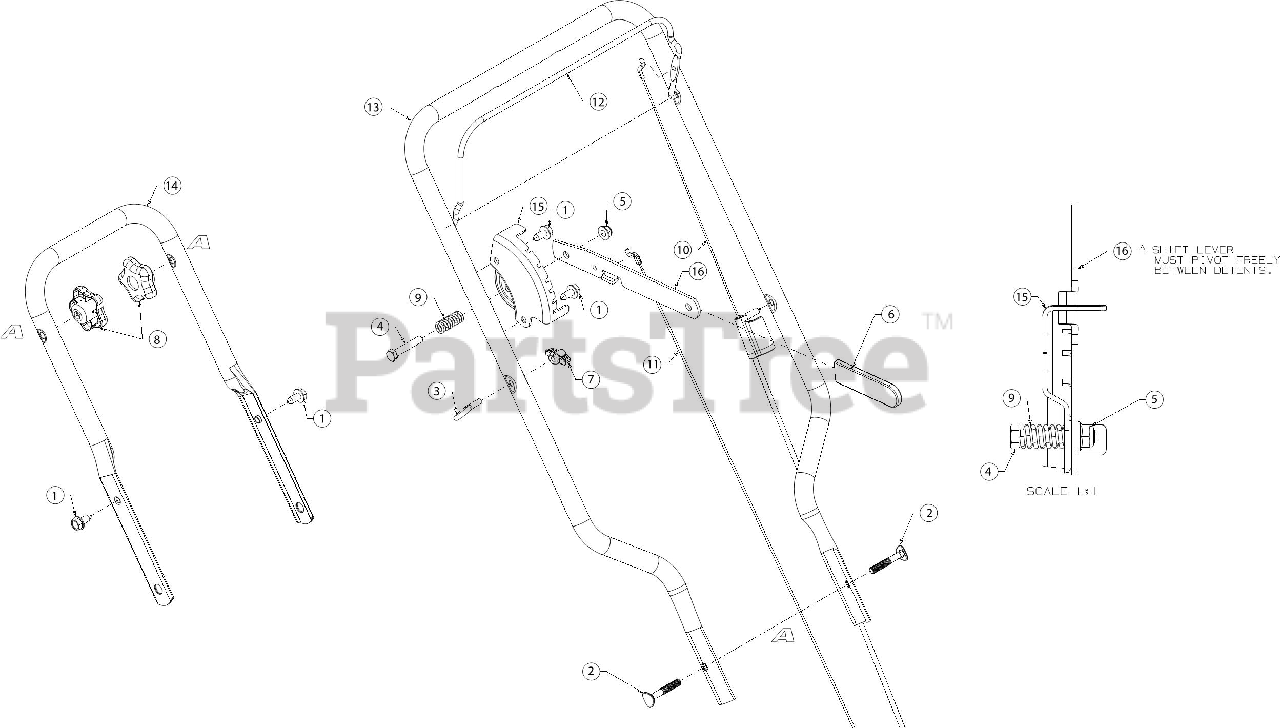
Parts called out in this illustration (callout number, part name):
1	SCREW 5/16-12 X .750
2	SCREW 5/16-18 X 2.0
3	EYEBOLT 1/4-20
4	SCREW 5/16-18 X 1.75 GR5
5	FLANGE LOCK NUT 5/16-18
7	HANDLE KNOB
8	STAR KNOB 5/16-18
10	CONTROL CABLE 23"
11	WHEEL ADJUSTMENT CABLE
12	BLADE CONTROL BAIL
